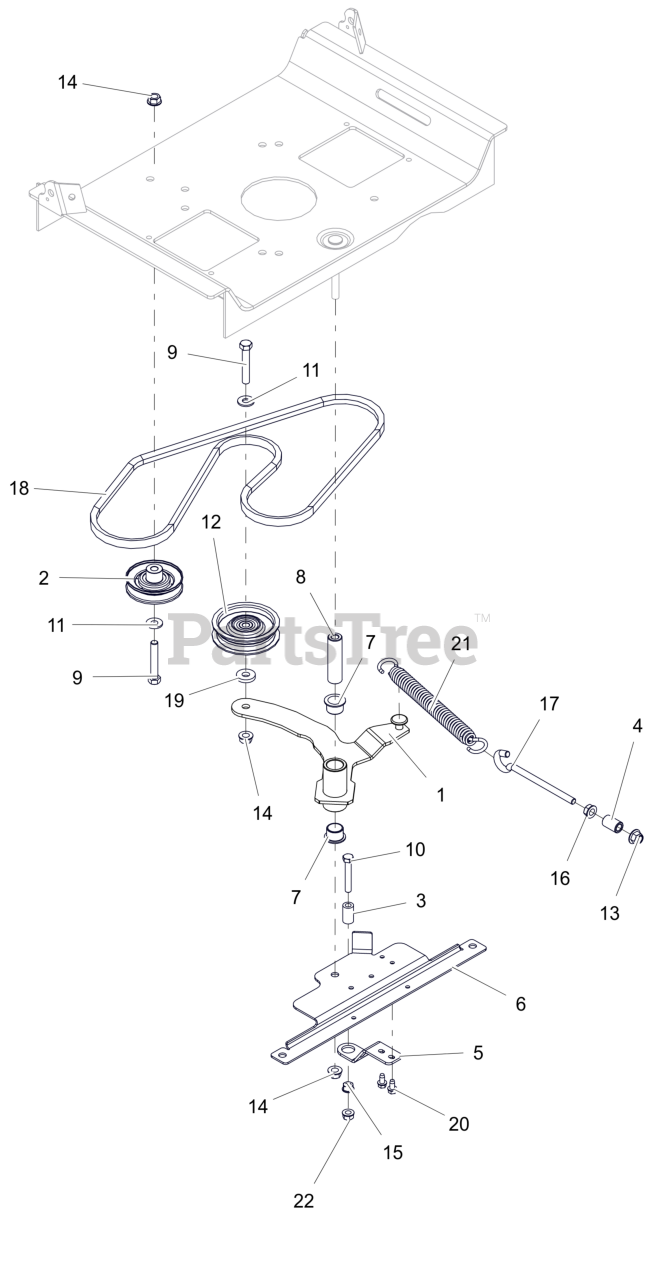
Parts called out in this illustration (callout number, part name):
1	WLDMT,GRD DRIVE IDLER ARM-LGR
2	IDLER, V-3.000 OD
3	SPACER, RUBBER 5/16 IDX1.0 LG
4	SPACER, .375X.625X.970 (PM)
5	BRKT, CLUTCH STOP (XL)
6	BRKT-IDLER ATTACHMENT
7	BSHG-FLG 0.75X0.875X.625X1.125
8	BUSHING, SLEEVE .38X.750X2.78
9	BLT,HEX .38-16X2.25 G5 ZCC
10	BLT, HEX .31-18X2.00 G5 ZCC
11	WSHR,FLT .375X.875X.083 ZCC
12	SHEAVE, IDLER -V .38 x 4.00
13	NUT,NYL-FLG .38-16 GF ZCC
14	NUT-LK-TOP-FLG .38-16 ZC120
15	NUT,SPNLK-FLG .31-18 G5 ZCC
16	NUT, SPNLK-FLG .38-16 G5 ZCC
17	BOLT,.38-16 X 4.25-.62 DIA EYE
18	V-BELT, A-RAW EDGE
19	WSHR, FLT .406X1.00X.188 ZCC
20	SCR-TAP .25-20X.50 HWH ZCC
21	SPRING, EXTENSION
22	NUT-LK-TOP-FLG .312-18 GF ZCC
